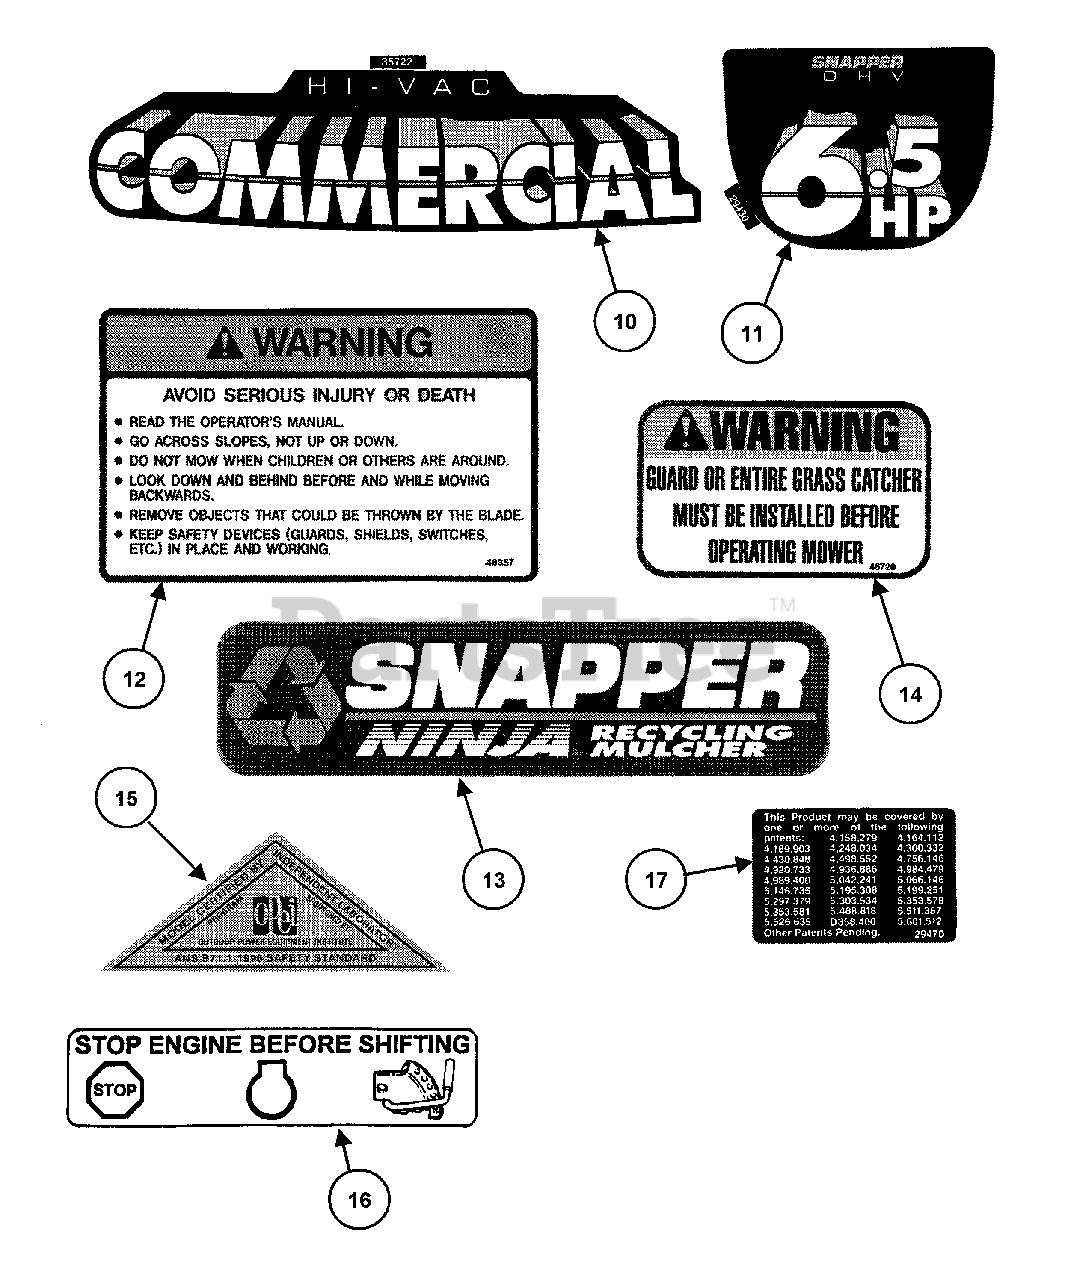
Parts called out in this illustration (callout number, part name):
10	DECAL, Hi-Vac/Commercial
11	DECAL, 6.5 Engine
12	DECAL, Warning
13	DECAL, Recycling Mulcher (Ninja)
14	DECAL, Chute
15	DECAL, OPEI
16	DECAL, Shifter
17	DECAL, Patent
